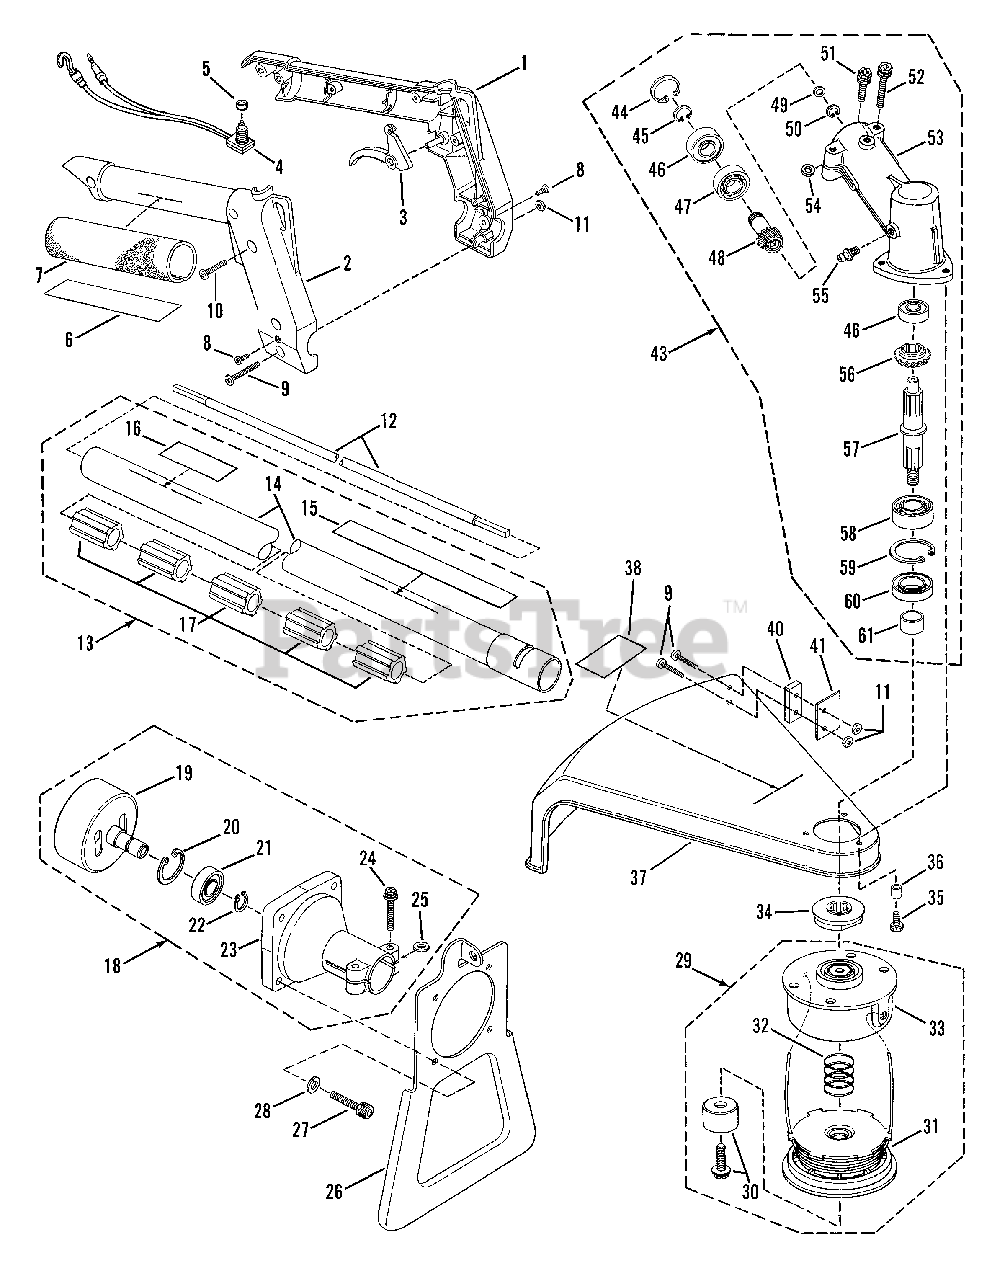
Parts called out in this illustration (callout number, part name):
1	HANDLE, Left Half
2	HANDLE, Right Half (was 19760)
3	TRIGGER
4	SWITCH
5	CAP, Switch
6	STRIP, Adhesive
7	GRIP, Handle
8	SCREW, TORX, #6x5/16"
9	SCREW, #10-32x7/8"
10	SCREW, #10-16x3/4"
11	LOCKNUT, #10-32
12	SHAFT, Main (55.12"x.25", .2" square ends x 1")
13	ASSEMBLY, Tubing & Bushing
14	TUBE
15	DECAL-SNAPPER
16	DECAL-WARNING (Eye Protection)
17	ISO-BUSHING
18	CLUTCH CASE ASSM'Y.
19	DRUM, Clutch 5.1" Square Hole
20	SNAP-RING, 28mm
21	BEARING
22	SNAP-RING, 12mm
23	CASE, Clutch
24	BOLT, M5x25mm H.H., w/Washers
25	WASHER, Shim
26	STAND, Engine
27	SCREW, M6x25mm Socket
28	LOCKWASHER
29	BUMP HEAD ASSM'Y.,
30	KNOB & BOLT
31	SPOOL & LINE
32	SPRING
33	HUB ASSEMBLY
34	HOLDER
35	BOLT, M5x16mm
37	SHIELD
38	DECAL, Replacement Part
40	BLOCK, Mounting
41	CUTTER, Line
43	GEAR HEAD ASSM'Y.,
44	SNAP-RING, 26mm
45	SNAP-RING, 10mm
46	BEARING
47	BEARING
48	BEVEL PINION
49	WASHER, Flat
50	SNAP-RING, 10mm
51	BOLT, M5x12mm Hex Hd.
52	BOLT, M5x25mm H.H.
53	GEAR CASE
55	FITTING, Lube
56	BEVEL GEAR
57	SPLINE SHAFT
58	BEARING
59	SNAP-RING, 35mm
60	SEAL, Oil
61	SPLINE SLEEVE
